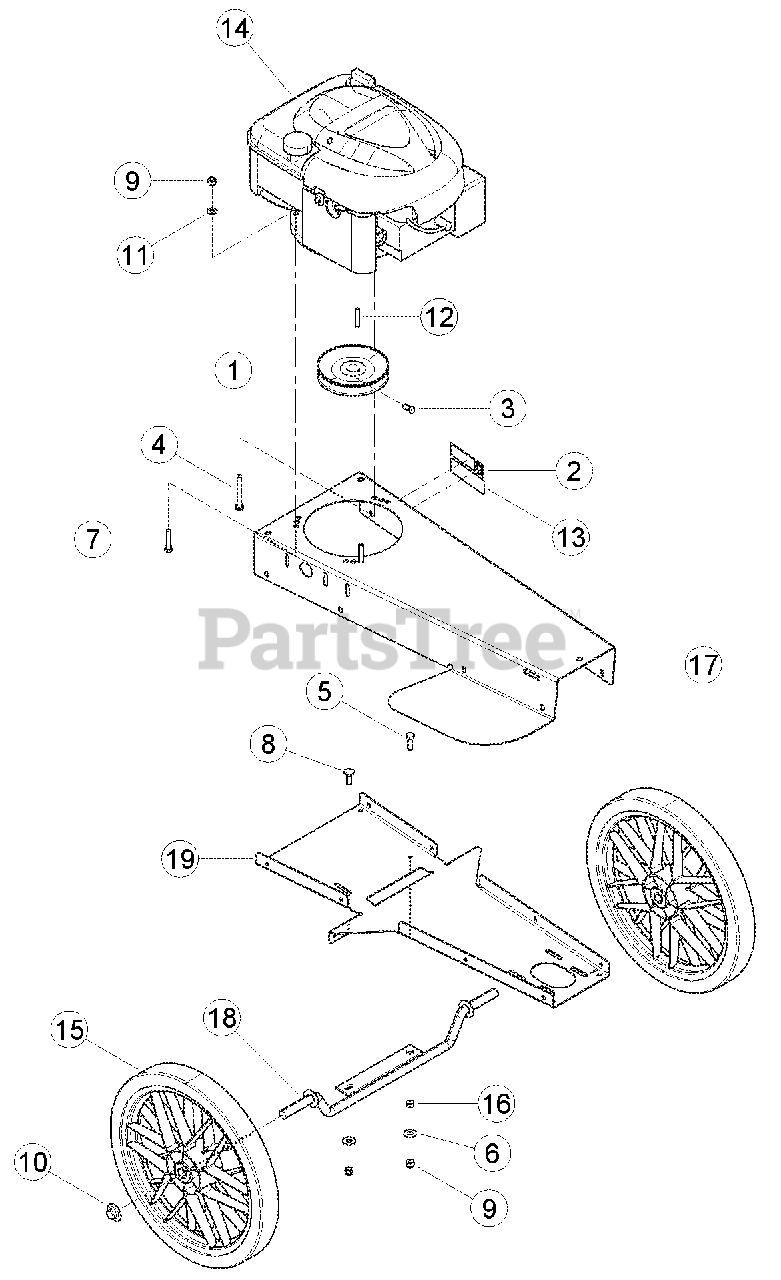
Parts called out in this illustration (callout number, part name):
1	PULLEY, 5.0 X 7/8 AB
2	DECAL, 6.5 HP INFORMATION
3	SCREW, 5/16-18 X 5/8 SQ HD SET
4	BOLT, 5/16 X 2-1/2 HEX HD GR5 ZP
5	BOLT, 5/16 X 1 HHCS GR5 NC ZP
6	WASHER, 5/16 FLAT ZP
7	BOLT, 5/16 X 1-1/2 HEX HD GR5 ZP
8	BOLT, 5/16 X 1 CRG GR5 ZP
9	NUT, 5/16 NE NYLOCK ZP
10	PUSHNUT, 5/8 ZP
11	WASHER, 5/16 SAE FLAT ZP
12	KEY, 3/16 SQUARE X 1-1/2 LONG PLAIN
13	DECAL, SERIAL NUMBER
14	ENGINE, 6.5 HP QUANTUM HD 49 STATE (CALIF. EMISSION COMPLIANT) (FOR SERVICE SEE ENGINE OWNER'S MANUAL OR YOUR NEAREST AUTHORIZED HONDA ENGINE DEALER.)
15	WHEEL, 15 INCH TRIMMER (BLACK)
16	SPACER, IDLER PIVOT
17	BODY, TRIMMER
18	WELDMENT, TRIMMER AXLE
19	BOTTOM, TRIMMER FRAME
